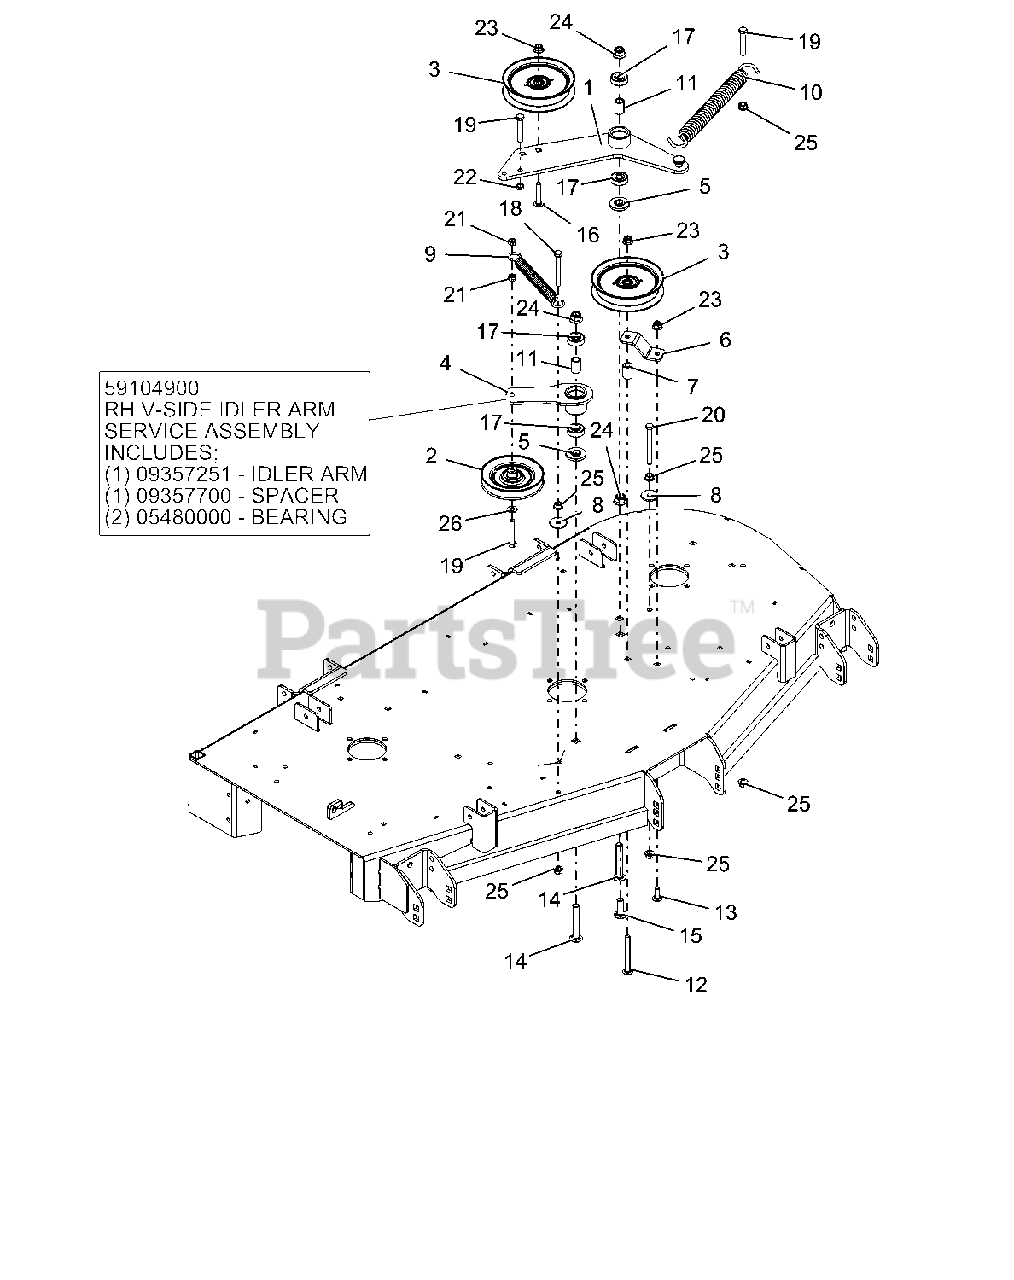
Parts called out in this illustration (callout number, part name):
1	DECK PTO IDLER ARM WLDMT - BLK
2	IDLER, V-5.00"
3	IDLER, FLAT 5.00"
4	BRG-BALL .50X1.38X.438 SEALED
4	SPACER .510 X .75 X 1.1485
4	DECK RH IDLER ARM WMT - BLK
4	RH V-SIDE IDLER ARM ASSEMBLY
5	SPACER, IDLER ARM
6	PTO FIXED IDLER MTG BRKT -RED
7	BUSHING, SLV .380X.750X1.190
8	WSHR-FL-STL .406X1.375X.135 YZ
9	SPRING, EXTENSION
10	SPRING, EXTENSION
11	SPACER .510 X .75 X 1.1485
12	BLT-RHDSSQNK .38-16X3.50 G5YZ
13	BLT-RDHDSHSQNK.38-16X1.0 G5YZ
14	BLT,RDHDSQSHNK.50-13X3.25 G5YZ
15	BLT-RDHDSHSQNKFT.50-13X1.50 G5
16	BLT-RDHDSQNK .38-16X2.00 SHTYW
17	BRG-BALL .500X1.38X.437
18	BLT-HEX .38-16X3.00 GR5 YWZC
19	BLT-HEX .38-16X2.25 GR5 YWZC
20	BLT-HEX .38-16X3.50 GR5 YWZC
21	NUT-LK-CTR .38-16 YWZC
22	NUT-HEX-JAM .375-16 YWZC
23	NUT-LK-NYL-FLG .38-16 YWZC
24	NUT-LK-NYL-FLG .50-13 YWZC
25	NUT-SPNLK-FLG .375-16 YWZC
26	WSHR-FL-STL.406X.812X.065 YWZ
